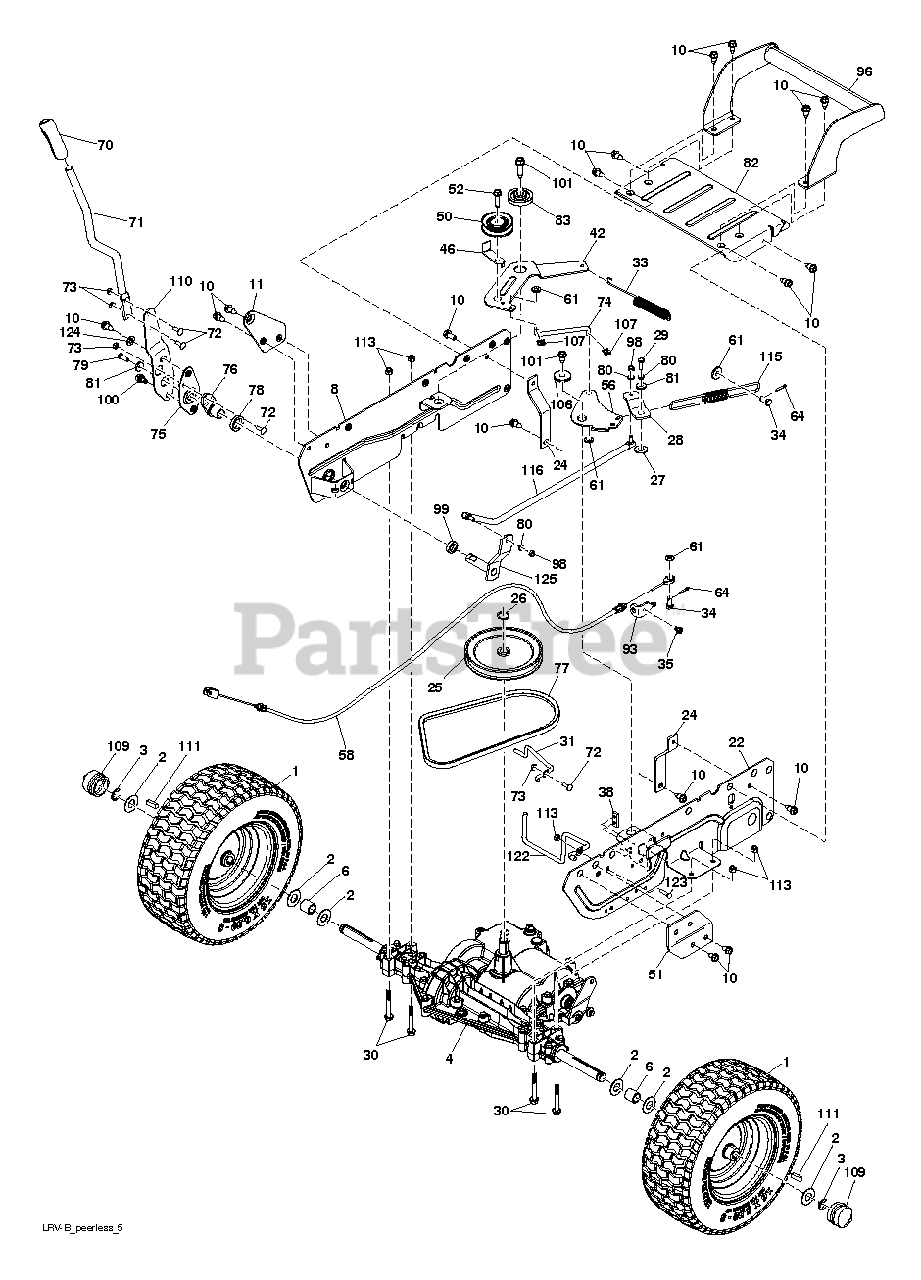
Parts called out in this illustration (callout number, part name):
1	WHEEL.TUBE.16X5.50-8.YELLOW.SN
3	E-RING LT
4	TRANSMISSION 4SPD MST 204-583A
6	SPACER, AXLE PVST
8	WELDMENT.SIDEPLATE.RH.X431
10	SCREW
11	BRACKET.SUPPORT.RH
22	WELDMENT.SIDEPLATE.LH.X431
24	STRAP.TORQUE.PMST.LRVB.PNT.431
25	PULLEY.INPUT.LRVB.PMST
26	RETAINING RING LT
27	WASH-SHFT PLT LT
28	ARM.SHIFTER.GEARDRIVE.PNT.431
29	Bolt, 1/4-20 unf Grade 8 w/Patch
31	Drive Belt Keeper, Lrvb.X431
33	Tensioner Spring
34	PIN.HEX.CROSSDRILLED.3125
35	SCREW.1/4-20X3/8
38	PLATE NUT ZTR
42	ARM.CLUTHCHING.LRVB..PNT.431
46	KEEPER.BELT.CLUTCHING.ARM.X431
50	PULLEY.V-IDLER.GRND.DR
51	BRACKET SUPPORT.LH
52	Bolt, 5/16-18 X 1.25
56	BELLCRANK GROUNDDRIVE.LRVB.431
58	Brake Cable, LRVB Pmst
61	WASHER
64	COTTER PIN
70	GRIP.HANDLE.LIFT.PVC.BLACK
71	TUBE.SHIFT.LRVB
73	NUT.CROWNLOCK.1/4
74	LINK.CLUTCHING.ARM.BELLCRANK
75	MNTG BRKT. SHIFT ARM
76	HUB.SHIFT
77	Drive Belt, Ground.Lrvb.Pmst
78	SPACER.NYLON.
80	LOCKWASHER
81	WASHER LT
82	COVER.REAR.LRVB.PMSTX431
83	SPACER.RETAINER
93	BRAKE.MOUNT.CABLE.LRV
98	NUT LOCK CENTER 1/4 -28 FNTHD
99	SPACER.ARM.SHIFTER
100	BOLT.SHOULDER.5/16-18X
101	SCREW 3/8-16 X 1-1/2
106	SPACER.RETAINER
107	CLIP RETAINER
109	CAP.AXLE.FRONT.YELLOW
110	BRACKET, SHIFTER FLEX
111	SQUARE KEY
113	NUT LOCK HEX FLANGE 5/16-18
115	SPRING.BRAKE.ENGAGE.LRVB.PMST
116	LINK.STUD.BALL.GEARDRIV
122	Engine Belt Keeper, LRV Gen2
123	BOLT
124	WASHER.SRRTD.5/16
125	SUBASM.SHAFT.SIFT.GEARDRVE.431
